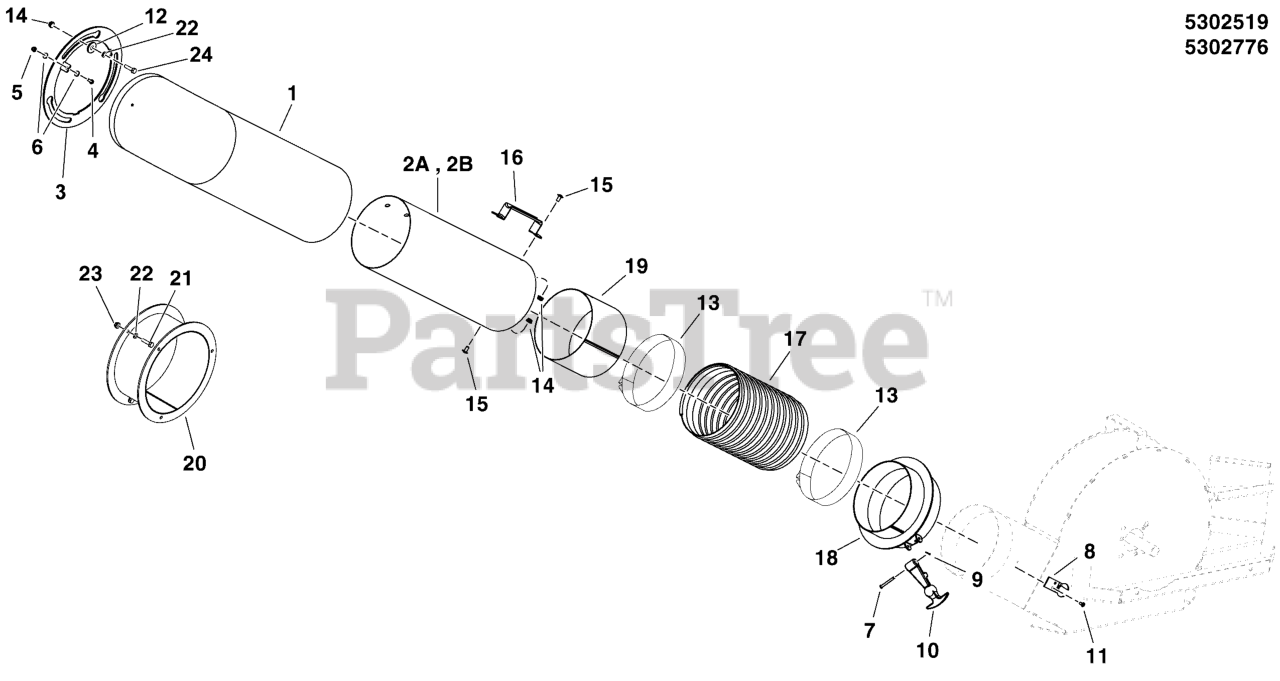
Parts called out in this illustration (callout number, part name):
1	ELBOW, ABS PLASTIC, HOPPER
2A	TUBE, IS3100Z, FAST-VAC
2B	TUBE, S800X, FAST-VAC
3	WELD, FLANGE ASSY - BLK
4	SCREW, #10-24 X 3/4 ROUND PHILLIPS
5	NUT, #10-24 HEX NYLON LOCK
6	WASHER, #10 SAE
7	PIN, CLEVIS
8	LATCH, RUBBER, KEEPER
9	PIN, COTTER
10	LATCH, RUBBER
11	RIVET-POP.188 .429L AL,AL STEM.37HD DIA
12	SPACER, STEP, HOPPER
13	CLAMP, HOSE, UPPER
14	NUT, 1/4-20 HEX NYLOCK FLANGE
15	SCREW, 1/4-20 X 1/2 ALLEN BH
16	HANDLE CONNECT TUBE, BLACK TEXTURED
17	HOSE, FLEXIBLE, FAST-VAC
18	WELD, HOSE ATTACHMENT - BLK
19	WELD, THIMBLE, BAGGER - BLK
20	WELD, ELBOW EXTENSION, HOPPERS - BLK
21	BOLT, 1/4-20 X 1" GD5 CZ
22	WASHER, 1/4 SAE
23	NUT, 1/4-20 HEX NYLOCK FLANGE
24	BOLT, 1/4"-20 X 3/4" GD5 YZ
